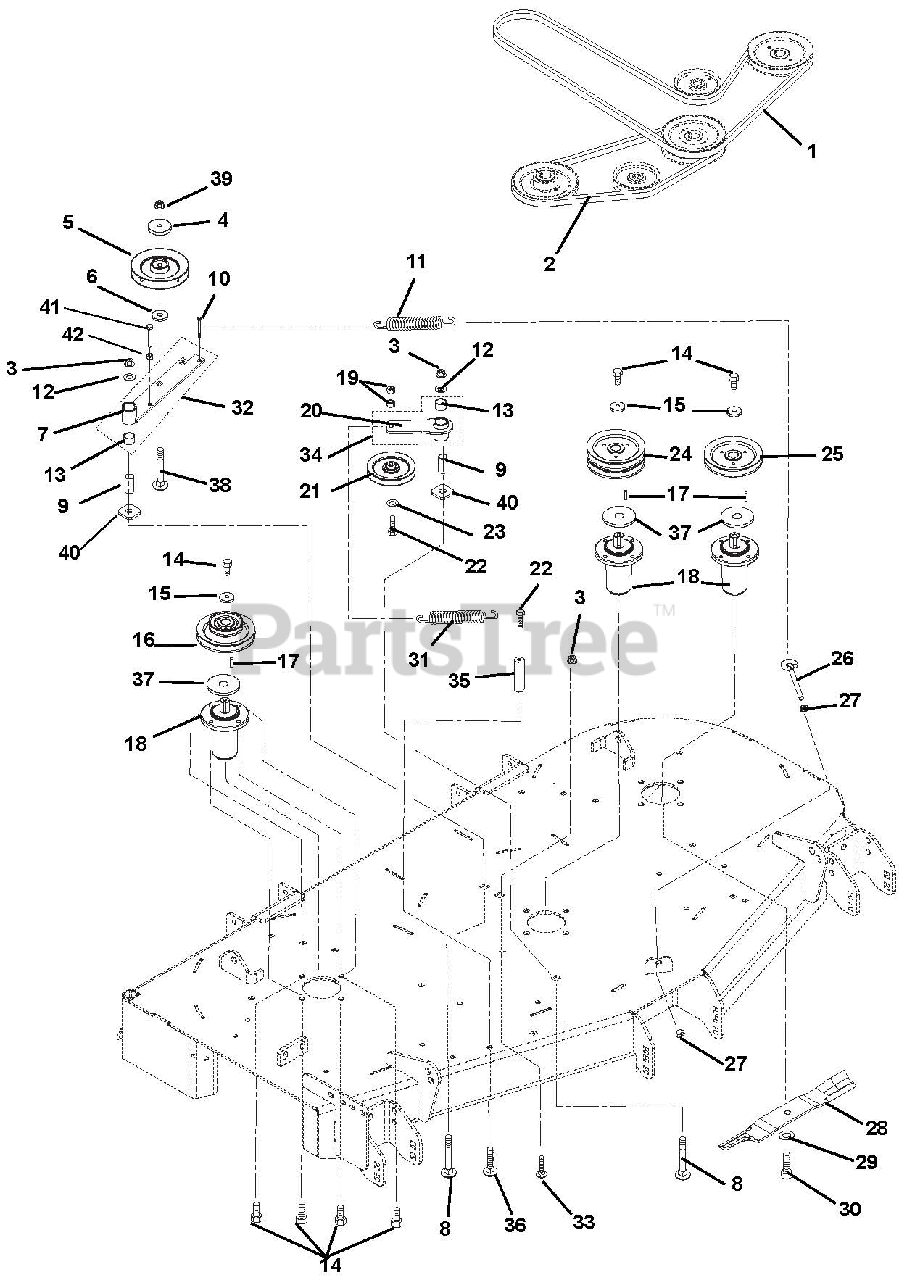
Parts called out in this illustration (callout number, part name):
1	Belt, 120.50" Long, PTO Drive Hex
1	Belt, 130" Long, PTO Drive Hex
1	Belt, 137" Long, PTO Drive Hex
1	Belt, 147" Long, PTO Drive Hex
2	V-Belt, 56" Long Cog B-Section
2	V-Belt, 63" Long Cog B-Section
2	V-Belt, 68" Long Cog B-Section
2	V-Belt, 76" Long Cog B-Section
3	Nut, .50-13 Nyloc Flange
4	Cap, Idler Bearing Sealing
5	Pulley, V 6.0 x .500 ID SNGL Bearing
6	Bushing, Spacer .502 x .997 x .50
7	Weldment, Idler Arm
8	Bolt, Round Head Square Neck .50-13 x 3.50
9	Bushing, Spacer .502 x .997 x 2.03
10	Bolt, Shoulder .38-16 x .30 Hex
11	Spring, Extension
12	Washer, Flat Steel .531x 1.250 x.100
13	Bushing, 1.00 x 1.125 x 1.936
14	Bolt, Hex .38-16 x 1.00
15	Washer, Flat Steel .406 x 1.50 x .245
16	Sheave, Double, 1" ID x 6" OD and 3.50" OD
16	Sheave, Double, 1" ID x 6.75" x 4.35" OD
16	Sheave, Double 1"ID x 7.25" and 4.75"OD
16	Sheave, Double, 1" ID x 8.25" and 5.25" OD
17	Key, Square .25 x .25 x 1 RC 40-50
18	Spindle Assembly
19	Nut, Locking-Center .38-16
20	Weldment, Idler Arm
21	Assembly, V-Idler 5.00 O.D.
22	Bolt, Hex .38-16 x 2.25
23	Washer, Flat Steel .406 x .812 x .065
24	Sheave, Double 1" ID x 6.00" OD
24	Sheave, Double 1" ID x 6.75" OD
24	Weldment, Sheave (Double) 7.25
24	Sheave, Double 1" ID x 8.25" OD
25	Sheave, Single 1" ID x 6.00" OD
25	Sheave, Single 1" ID x 6.75" OD
25	Sheave, Single 1"ID x 7.25" OD
25	Sheave, Single 1"ID x 8.25" OD
26	Bolt, .38-16 x 4.50 .62 Diameter Eye
27	Nut, Hex, Jam .375-16
28	Blade, 18.00" Mower
28	Blade, Mower, 20.50"
28	Blade, Mower, 22.50"
28	Blade, Mower (24.50") without Tungsten Carbide Hardfacing
29	Washer, Bellville .63 x 1.625 x.14
30	Bolt, Hex .62-18 x 1.75 Grade 8
31	Spring, Extension
32	Assembly, PTO Idler Pivot Arm
33	Bolt, Round Head Square Neck .50-13 x 1.5, Full Thread, Grade 5
34	Assembly, Idler Pivot Arm
35	Nut, Coupling .375-16 x 1.75
36	Bolt, Round Head Square Neck .38-16 x 1.00
37	Retainer, Grease
38	Bolt, Round Head Square Neck .50-13 x 3.00 Grade 5
39	Nut, Locking Center .50-13
40	Washer, Flat .640 x 1.75 x .250
41	Bolt, Hex .38-16 x 2.75
42	Nut, Hex .38-16
